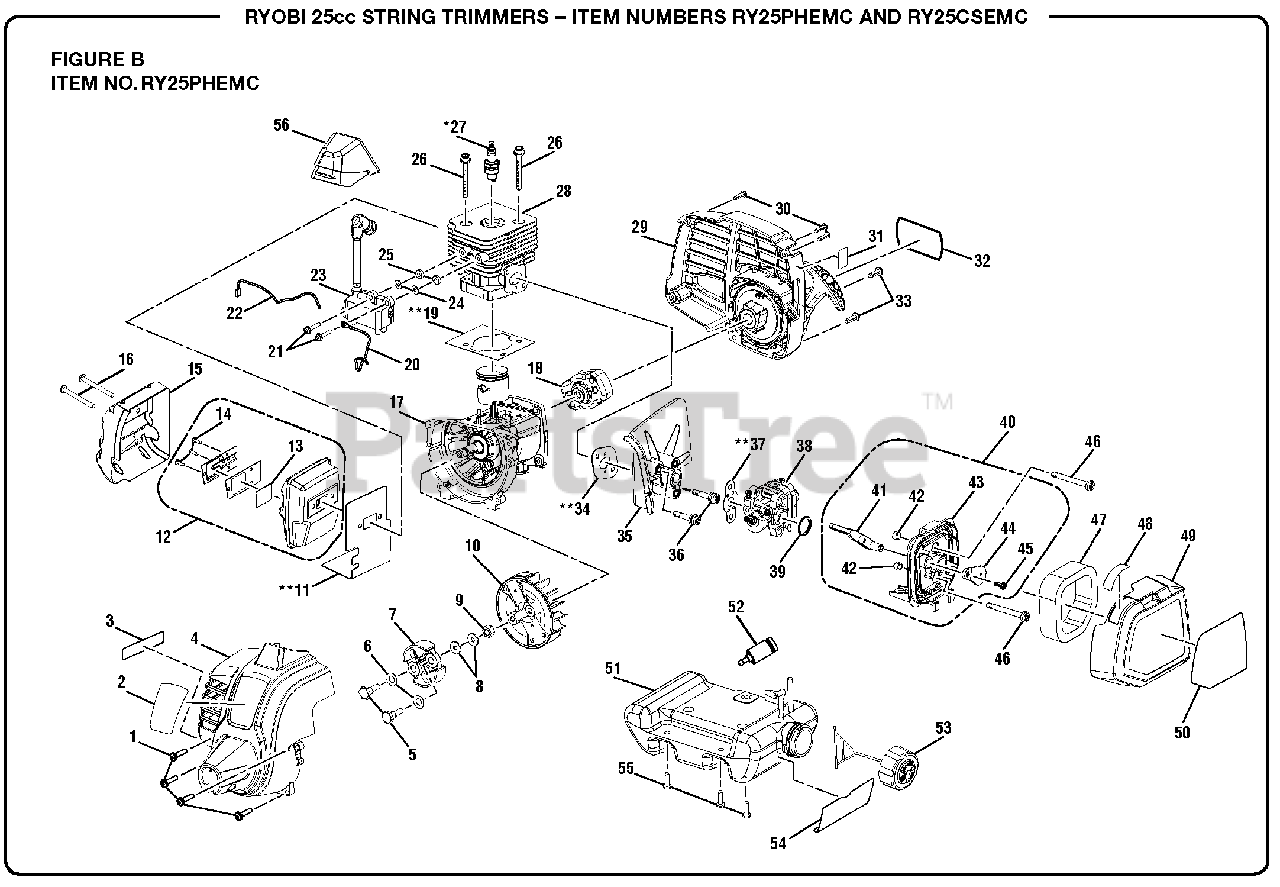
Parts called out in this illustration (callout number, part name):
1	Screw w/Washer (M5 x 20 mm, T20 Torx Pan Hd.)
2	Logo Label (Front)
3	Combustion Warning Label
4	Front Housing Assembly
5	Clutch Shoulder Bolt (M6 x 22.5 mm, Hex Hd.)
6	Curved Washer
7	Clutch Assembly
8	Washer (ID6 x OD15 x 1.2t)
9	Flywheel Nut
11	Muffler Gasket
12	Muffler Assembly
13	Screen
14	Screw (6-20 x 1/4 in., T20 Torx Pan Hd. S.T.)
15	Heat Shield
16	Screw (M5 x 50 mm, T25 Torx Pan Hd.)
17	Crankcase Assembly
18	Starter Cup
19	Gasket
20	Lead Wire (Red)
21	Screw w/Washer (M4 x 22 mm, T20 Torx Pan Hd. S.T.)
22	Lead Wire (Black)
23	Coil Boot Assembly
24	Washer (ID4.2 x OD10 x 1t)
25	Spacer (Phenolic)
26	Screw (M5 x 22 mm, Soc. Hd.)
27	Spark Plug (Champion RCJ6Y)
29	Rear Housing and Starter Assembly
30	Screw (M4 x 18 mm, T20 Torx Pan Hd. S.T.)
31	Primer Bulb Location Label
32	Logo Label (Rear)
33	Cap Screw w/Washer (M5 x 16 mm, T25 Torx Soc. Hd.)
34	Insulator Gasket
35	Heat Dam Insulator
36	Screw (M5 x 30 mm, T25 Torx Pan Hd. S.T.)
37	Gasket
38	Carburetor Assembly
39	Carburetor O-Ring
40	Airbox Base Assembly
41	Choke Lever
42	Compression Limiters
43	Air Box Base
44	Choke Plate
45	Screw (M4 x 12 mm, T20 Torx Pan Hd. S.T.)
46	Screw (M5 x 44 mm, T20 Torx Pan Hd.)
47	Air Filter
48	Choke Position Label
49	Airbox Cover
50	Starting Instructions Label
51	Fuel Tank and Cap Assembly
52	Fuel Filter
53	Fuel Cap Assembly
54	Fuel Mixture Label
55	Shoulder Screw (M4 x 14 mm, T25 Torx Truss Hd. S.T.)
56	Spark Plug Boot
